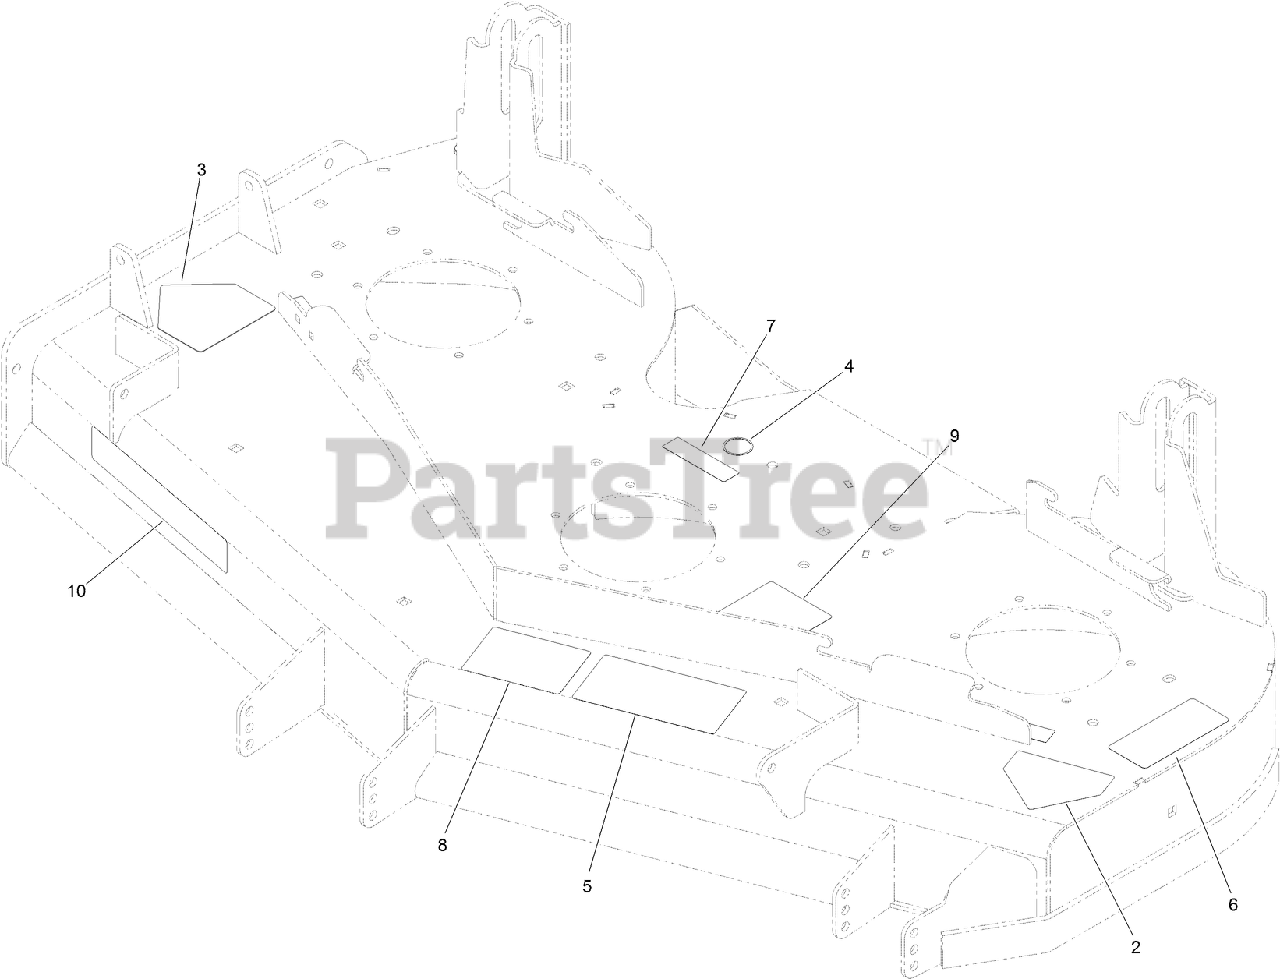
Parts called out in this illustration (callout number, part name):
2	DECAL-DANGER
3	DECAL-DANGER
4	DECAL-GREASE
5	DECAL-DANGER, THROWN OBJECT
6	DECAL-TORQUE
7	DECAL-COVER, MISSING
8	DECAL-SCALP, ANTI
9	DECAL-ROUTING, DECK BELT
